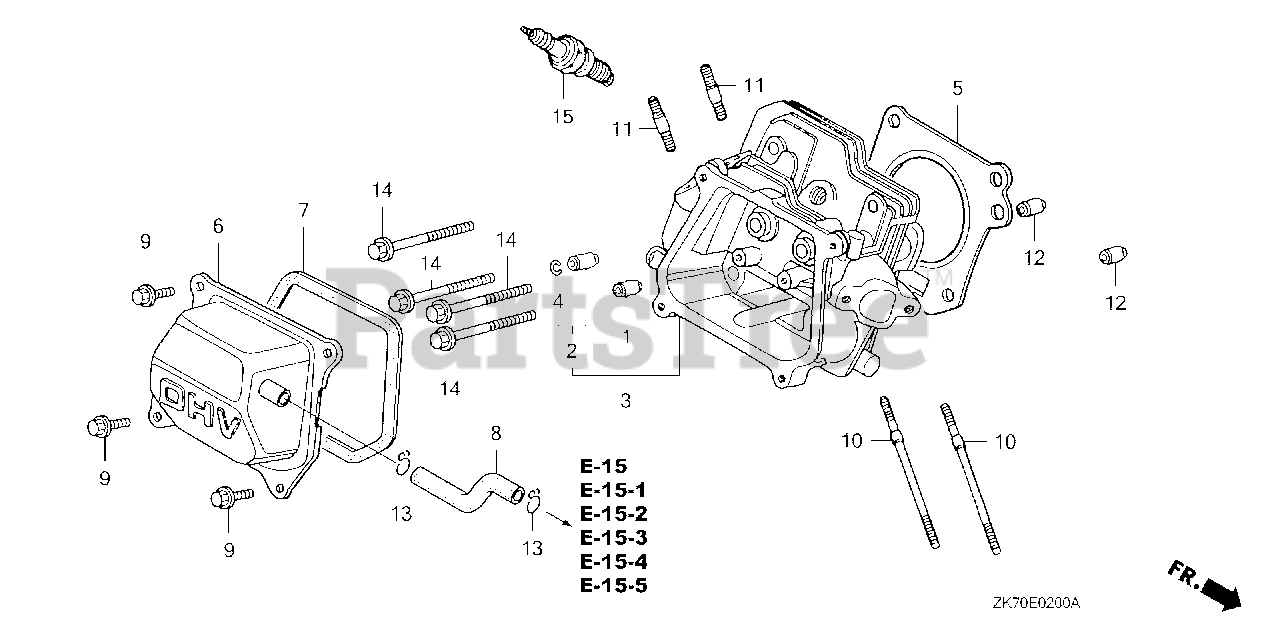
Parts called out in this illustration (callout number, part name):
1	GUIDE, VALVE (OVER SIZE) Use from Engine SN 6324986.
2	GUIDE, EX. VALVE (OS)
3	CYLINDER HEAD
4	CLIP, VALVE GUIDE Use from Engine SN 1231803.
5	GASKET, CYLINDER HEAD
6	COVER, HEAD
7	GASKET, CYLINDER HEAD COVER
8	TUBE, BREATHER
9	BOLT, FLANGE (6X12) (CT200)
10	BOLT, STUD (6X109)
11	BOLT, STUD (8X32)
12	PIN A, DOWEL (10X16)
14	BOLT, FLANGE (8X55)
15	SPARK PLUG (BPR5ES) (NGK)
15	SPARK PLUG (W16EPR-U) (DENSO)
15	SPARK PLUG (BPR6ES) (NGK)
15	SPARK PLUG (W20EPR-U) (DENSO)
